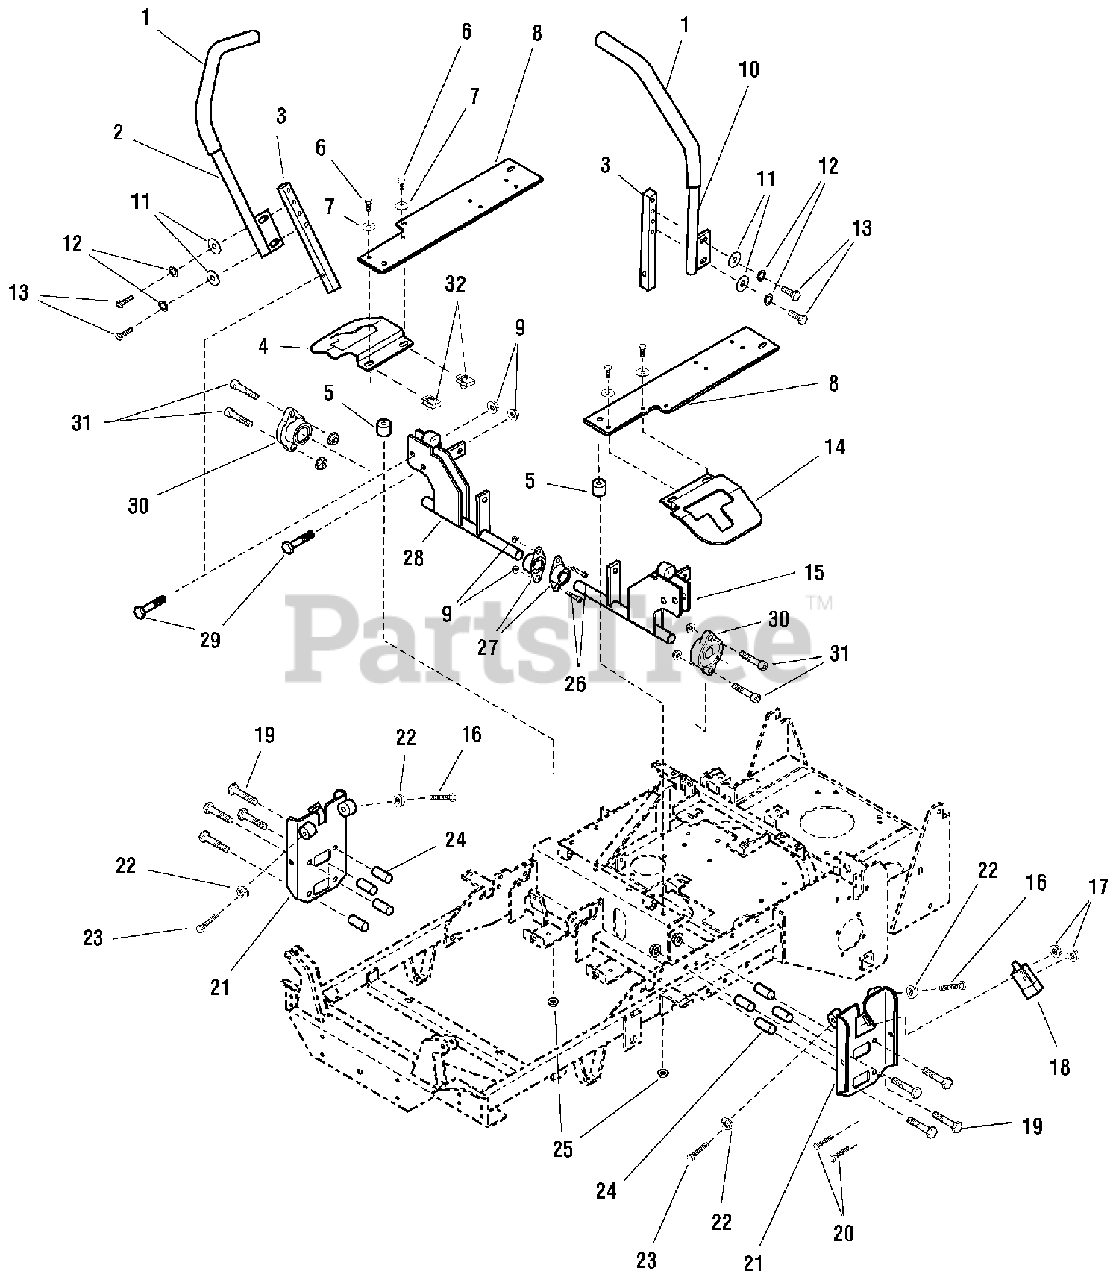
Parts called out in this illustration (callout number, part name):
1	FOAM GRIP
2	MOTION CONTROL LEVER - RH
3	CONTROL LEVER BASE
4	NEUTRAL LOCK PLATE COVER, RH
5	SPACER
6	CAPSCREW, Hex Head, 1/4-20 X 3/4
7	WASHER, 1/4 SAE
8	FAN SHIELD
9	NUT, HEX NYLON LOCK, 3/8-16
10	MOTION CONTROL LEVER - LH
11	WASHER, FLAT, 5/16
12	LOCK WASHER, 5/16
13	CAPSCREW, HEX HEAD, 5/16-18 X 1
14	NEUTRAL LOCK PLATE COVER, LH
15	WELD, CONTROL SHAFT LH
16	CAPSCREW, HEX HEAD, TFL, 5/16-18 X 2
17	NUT, HEX, #10-24
18	SWITCH, NO/NC
19	CAPSCREW, HEX HEAD, 5/16-18 X 2 1/4
20	SCREW, #10-24
21	WELD, PLATE, NEUTRAL
22	NUT, HEX SERRATED FLANGE, 5/16-18
23	CAPSCREW, HEX HEAD, TFL, 5/16-18 X 1-3/4
24	SPACER
25	NUT, HEX, SERRATED FLANGE, 3/8-16
26	BOLT, 3/8-16 X 1" GD5 CZ
27	BRONZE BEARING
28	WELD, CONTROL SHAFT RH
29	BOLT, 3/8-16 X 1-3/4" GD5 CZ
30	FLANGE BEARING
31	CAPSCREW, SOCKET HEAD, 3/8-16 X 1 1/4
32	BODY CLIP, 1/4-20
